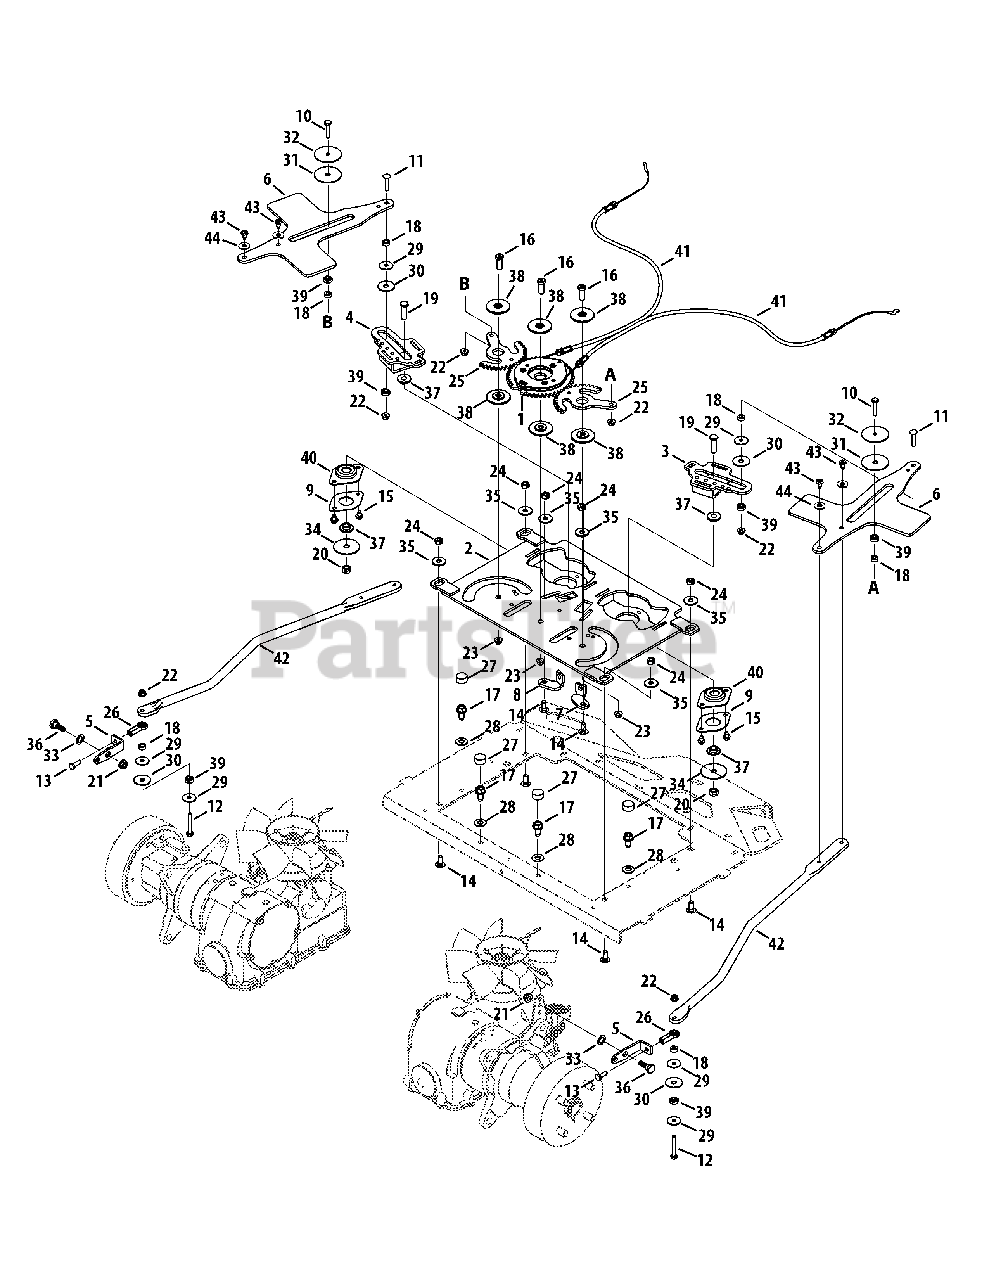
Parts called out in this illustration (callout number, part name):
1	Pump Control Gear
2	Pump Control Mounting Plate
3	Pump Control Cam Assembly, RH
4	Pump Control Cam Assembly, LH
5	Pump Control Bracket
6	Pump Steering Arm Actuator
7	Steering Cable Bracket
8	Steering Cable Bracket
9	Retainer Bearing Plate
10	Hex Cap Screw, 1/4-20 x 1.25
11	Carriage Screw, 1/4-20 x 1.25
12	Hex Cap Screw, 1/4-20 x 1.75
13	Hex Cap Screw, 1/4-28 x .75
14	Carriage Bolt, 5/16-18 x .75
15	Hex Flange Screw, 1/4-20 x .500
16	Socket Head Screw, 3/8-16 x 1.00
17	Screw, 3/8-16 x .75
18	Spacer, .256 x .500 x .240
19	Hex Cap Screw, 3/8-16 x 1.25
20	Nut, 3/8-16, Hexlock
21	Nut, 5/16-18, Flangelock
22	Nut, 1/4-20, Flangelock
23	Nut, 3/8-16, Flnagelock
24	Nut, 5/16-18, Hexlock
25	Yoke Steering Gear
26	Rod End, 1/4-28
27	Slide Cap
28	Washer, .406 x .875 x .059
29	Washer, .255 x 1.00 x .060
30	Washer, .355 x 1.25 x .060
31	Washer, .356 x 2.00 x .060
32	Washer, .260 x 2.00 x .060
33	Washer, .469 x .75 x .060
34	Washer, .406 x 1.92 x .060
35	Washer, .345 x 1.00 x .100
36	Shoulder Screw, .437 x .268, 5/16-18
37	Shoulder Spacer, .38 x 1.00 x .31
38	Shoulder Spacer, .853 x .385 x .100
39	Ball Bearing, .250 x .625
40	Ball Bearing, .625
41	Transmission Link Control Cable
42	Pump Control Rod
43	Shoulder Screw, .342 x .335, 1/4-28
44	Flat Washer, .344 x .688 x .065
